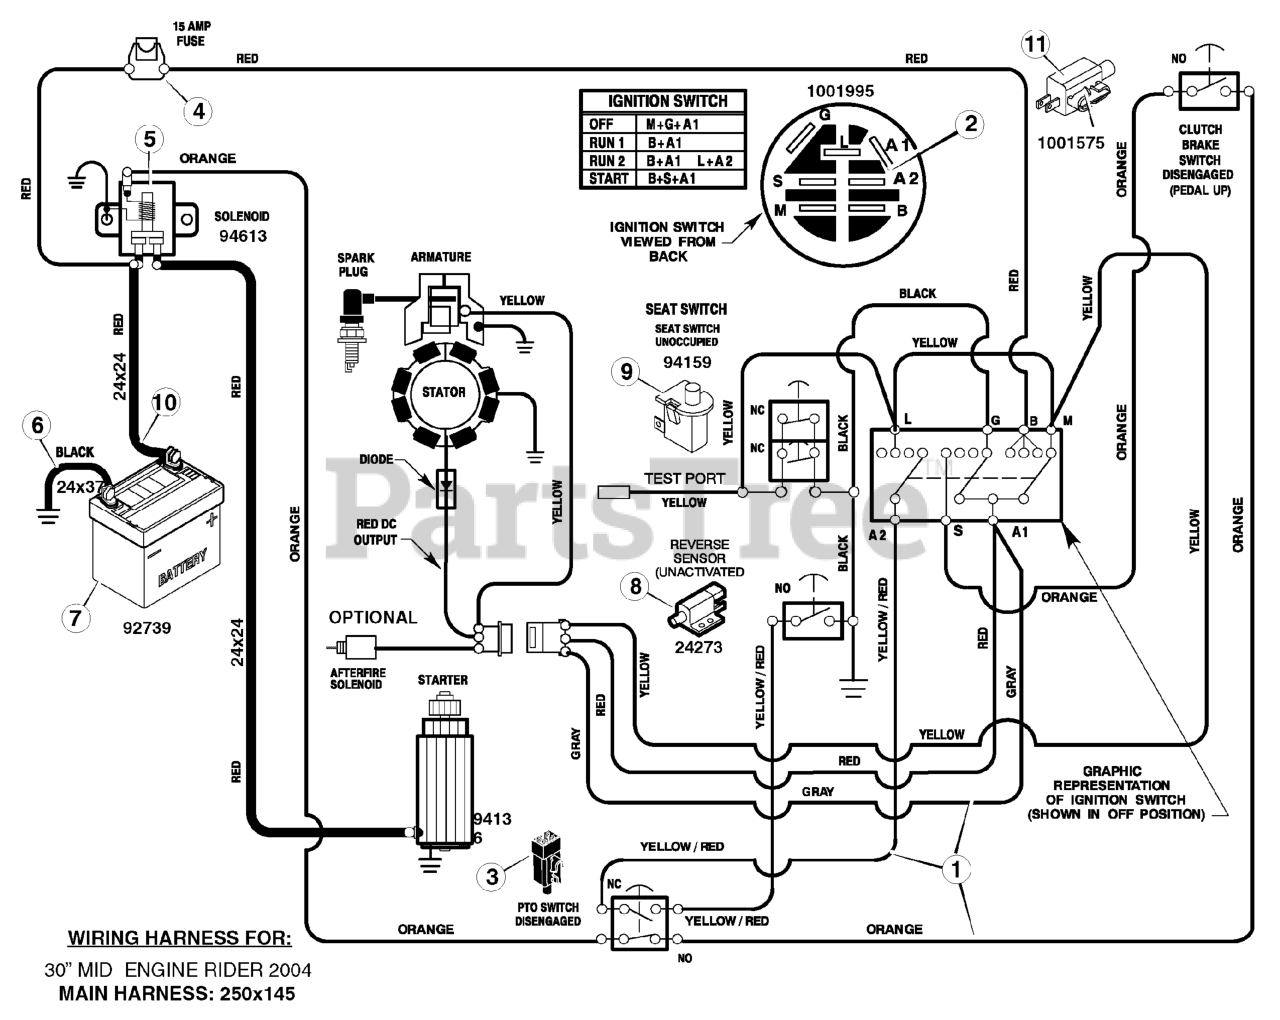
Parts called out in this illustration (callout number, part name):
1	HARNESS, Chassis Wire
2	SWITCH, Ignition
3	SWITCH, Limit (PTO)
5	SOLENOID
6	CABLE, Battery Ground
8	SWITCH, Select Reverse
9	SWITCH, Seat Sensor
11	SWITCH, Clutch Brake
